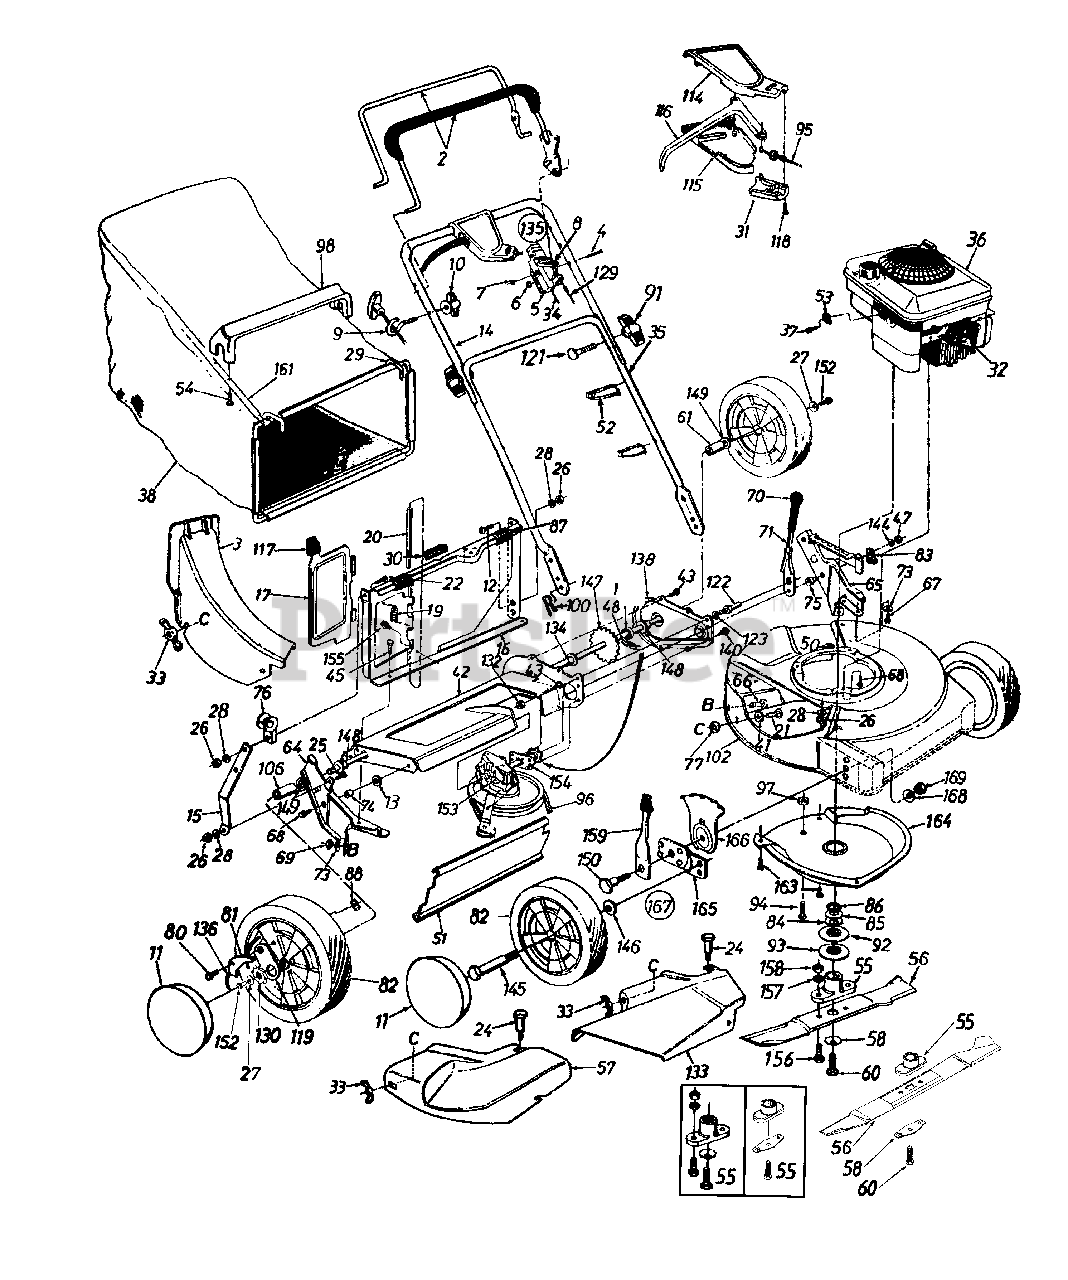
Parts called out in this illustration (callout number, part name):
1	Washer
2	Control Handle Ass'y.
3	Rear Discharge Chute Ass'y.
4	Oval C-Sunk Scr.
5	Throttle Body
6	Spr. Wash. .66" I.D.
7	Hex L-Nut 1/4-20 Thd.
8	Throttle Lever
9	Rope Guide
10	Wing Nut 1/4-20 Thd.
11	Hub Cap
12	Truss Mach. Scr. 1/4-20 x .75"
13	Fl-Wash. .383" I.D. x 1" O.D.
20	Pivot Pin
21	Carriage Bolt 1/4-20 x .62"
22	Truss Mach. Scr. 1/4-20 x .75"
24	Shoulder Bolt .312 Dia. x .18 Lg.-Special
25	Hex Bolt 1/4-20 x .62" Lg.
26	Hex Nut 1/4-20 Thd.
27	Bell-Wash. 1/4" I.D.
28	L-Wash. 1/4" I.D.
30	Foam Strip
31	S.P. Control Cover
32	Spark Plug Insulator
33	Wing Nut w/Washer
34	Throttle Control Wire 61"
36	Engine
37	Hex Self-Tap Scr. #10-32 x .62"
38	Grass Bag
41	Fl-Wash. .344" I.D. x .62"
45	Hex Tap Scr. 1/4 x .62"
47	Hex Patch L-Nut 3/8-24 Thd
48	#48 Chain .500" Pitch x 30 Lnk
51	Rear Flap
52	Cable Tie
53	Cable Clamp
54	Hex AB Scr. #12 x 1.25" L
55	Blade Adapter Kit
56	21" Mulching Blade
57	Mulching Plug
58	Bell-Wash. .39" I.D.
60	Hex Bolt 3/8-24 x 1.5" L. (Gr 5)
61	Spa. .513" I.D. x .703" O.D. x 69"L
67	Hx Wsh. Hd. B-Tap Scr. 5/16-18
68	Hx Wash. Hd. Tap Scr. 3/8-16
69	Hx Nut 5/16-18 Thd.
71	Height Adj. Lever
73	Bell-Wash. 5/16" I.D.
74	Spacer
75	Shld. Spacer .500" Dia.
76	Rope Guide
77	Bolt Retainer 1/4 x .50" O.D.
80	Shld. Scr. .342" Dia. x .268
81	Pawl L.H.
82	Wheel Ass'y. Comp.
83	Clamp
84	Fl-Wash. .88" I.D.
85	Spr.-Washer .89" I.D.
86	Crankshaft Spacer
87	Panel Clip
88	Weld L-Nut 1/4-20 Thd.
91	Hand Knob
92	Pulley Half-Upper
93	Pulley Half-Lower
94	Phil. Mach. Scr. 1/4-20
95	S.P. Cable
96	"V"-Belt
97	Sems Nut 1/4-20 Thd.
98	Bag Handle
100	Hairpin Clip
114	Self-Propelled Control Cover
115	Self-Propelled Control Cover
116	Control Lever
117	Door Grip
118	Fl-"C"-Sunk Hd. Tap Scr. #10 x .75" Lg.
119	Pawl Plate
121	Cur. Carr. Bolt 5/16-18 x 2" Lg.
122	Shld. Pin 3/8-24 x 1.43" Lg.
123	L-Wash. 3/8" I.D.
129	Control Cable 47" Lg.
130	Ratchet Wheel 1.62" O.D.
132	Hex Jam Nut 3/8-24 Thd.
133	Side Chute Deflector Ass'y.
134	Hex Flange Bearing
135	Throttle Box Comp.
136	Spring-Nylon
144	Fl-Wash. .385" I.D. x .87"
145	Axle Bolt
146	Bell-Wash. .4" I.D. x .88" O.D.
147	Rear Shaft Ass'y. 21.94" Lg.
148	Hex Flange Bearing .506" I.D. Plastic
149	Fl-Wash. .531" I.D. x .930"
150	Shld. Bolt .5" Dia. x .434"
152	Hex Bolt 1/4-20 x .62" L. (Gr. 5)
153	Transmission Comp.
155	Hex B-Tap Scr. #10 x .38
156	Hex Scr. 3/8-24 x 1.0" Lg.
157	L-Wash. 3/8" I.D.
158	Hex Nut 3/8-24 Thd.
159	Spring Lever Ass'y. w/Knob
163	HexIndWash Scr. 1/4-20: .375
166	Height Adj. Plate
167	Fr. Height Adj. Ass'y. Comp. - RH
168	Bell-Wash. .39" I.D. x 1.38" O.D.
169	Hex Nut 3/8-16 Thd.
